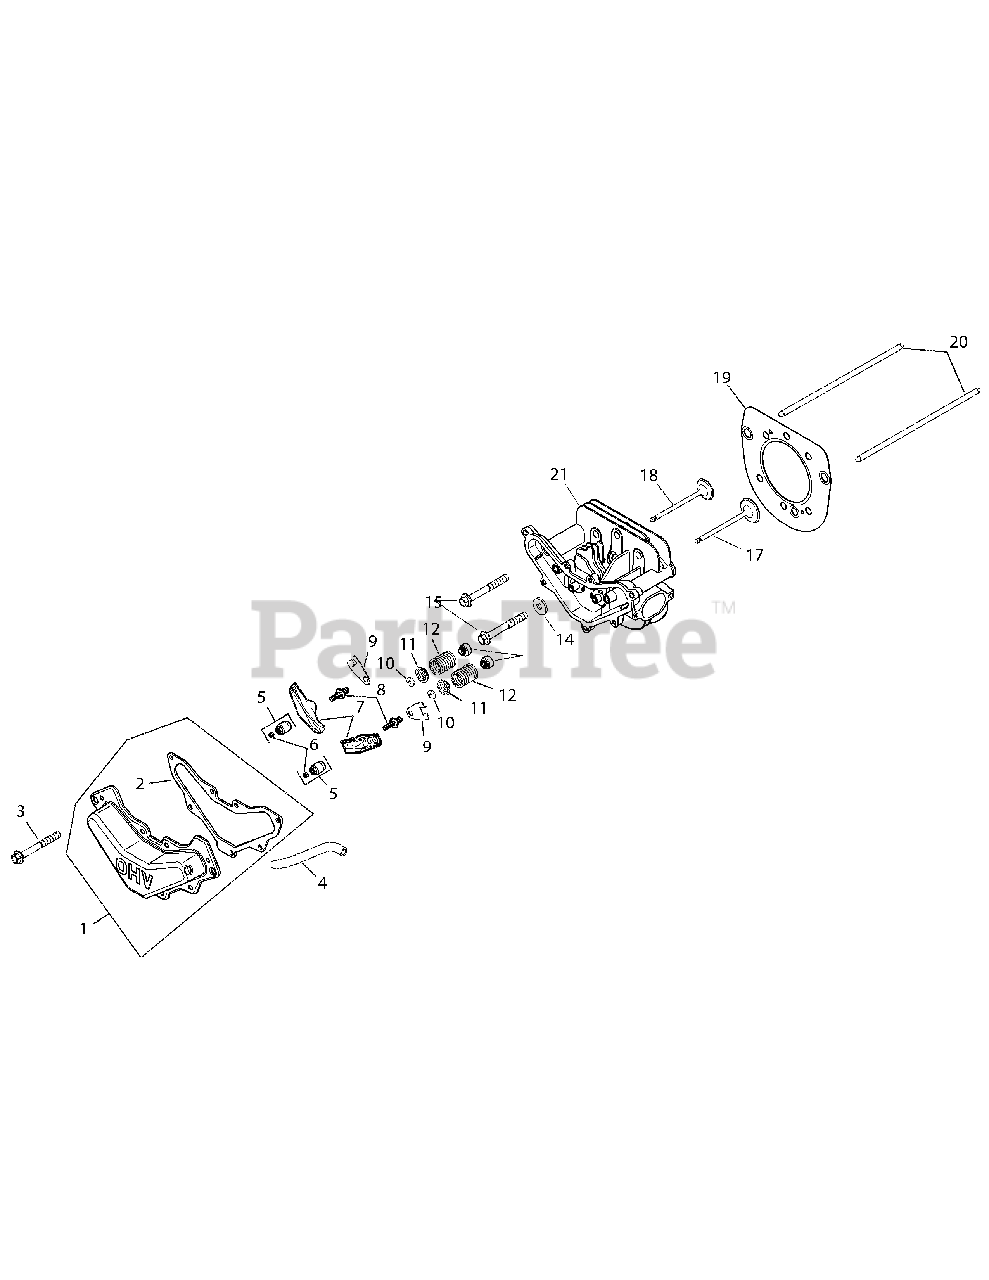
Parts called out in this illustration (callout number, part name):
1	Valve Cover Kit (Incl. 2)
2	Valve Cover Gasket
3	Flange. Screw, M6 X 1.0 X 20
4	Breather Hose
5	Rocker Pivot Assembly (Incl. 6)
9	Push Rod Guide Plate
10	Retainer Lock
11	Valve Spring Cap
14	Flat Washer, 13/32
15	Flange Screw, M10 X 1.5 X 80
17	Exhaust Valve
19	Cylinder Head Gasket Kit
20	Rod, Push
21	Kit, Cylinder Head (Incl. 28 & 29)
22	Kit Pivot, Rocker Arm (Incl. 6)
